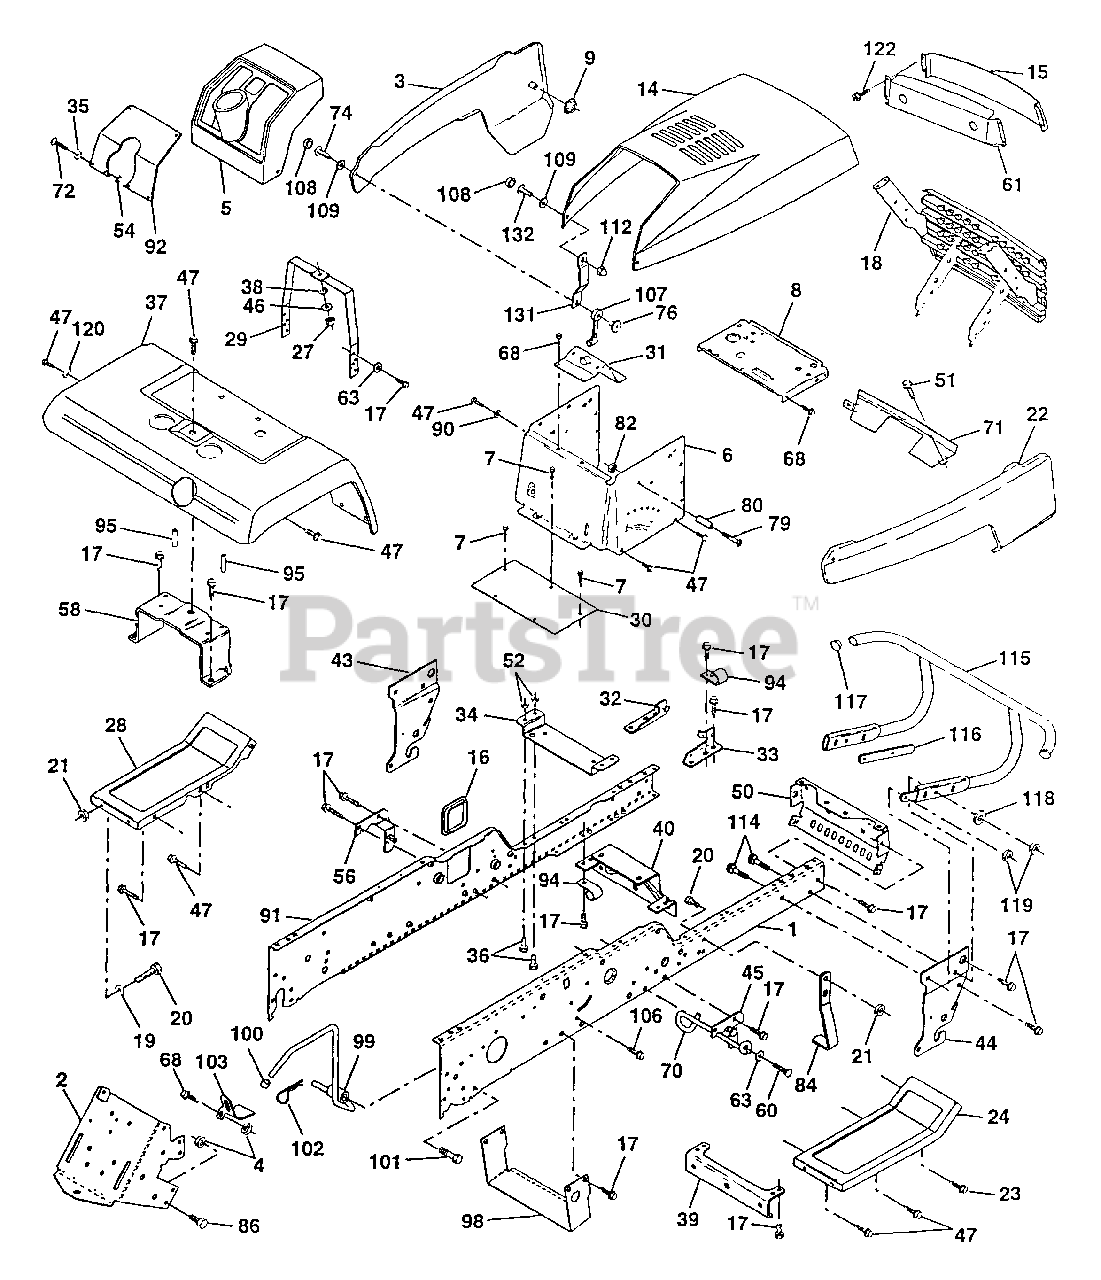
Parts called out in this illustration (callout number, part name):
1	Rail, Frame RH (AYP part number)
2	Drawbar, Gt (AYP part number)
3	Panel Asm., Side LH
4	Nut, Lock Hex 7/16 Unc
5	Dash, Plastic Black
6	Dash, 1PCS, Lower
7	Screw, Thd Cut 1/4-20 x 1/2
8	Support, Battery (AYP part number)
9	Nut, Pal
14	Hood Asm., Pnt
15	Lens, Headlight Bar
16	Cover, Access
17	Screw, Thdrol 3/8-16 x 3/4
18	Grille
19	Washer 13/32 x 13/16 x 12 Ga.
20	Bolt, Fin Hex 3/8-16 x 1
21	Nut, Crownlock 3/8-16
22	Panel Asm., Side RH (AYP part number)
23	Screw Thdrol 3/8-16 x 1
24	Footrest, RH (AYP part number)
27	Nut, Fin Hex 1/4-20
28	Footrest, LH
29	Bracket, Support Dash
30	Saddle
31	Bracket, Support Steering
32	Bracket Asm., Frame Pivot Lh
33	Bracket Asm., Frame Pivot Rh
34	Bracket, Engine Support Rear
35	Washer 11/32 x 11/16 x 16 Ga.
36	Bolt, Fin Hex 5/16-18 x 3/4
37	Fender, Pnt.
38	Washer, Lock 1/4
39	Bracket, Axle Front (AYP part number)
40	Bracket, Support Axle/Engine
43	Bracket, Spnsn Front Lh
44	Bracket, Spnsn Front Rh
45	Bracket Asm., Susp Chassis Rh
46	Washer 9/32 x 3/4 x 16 Ga.
47	Screw Thdrol 3/8-16 x 1/2
50	Bracket, Chassis Front
51	Screw Tap Tite 1/4-20 x 1/2
52	Nut, Crownlock 5/16-18
54	Nut 5/16-18
56	Bracket Asm., Susp Chassis Lh
58	Bracket Asm., Fender
60	Screw Thdrol 3/8-16 x 1-1/4
61	Beze. Asem. (AYP part number)
63	Washer 13/32 x 1 x 14 Ga. (AYP part number)
68	Screw, Thdrol 5/16-18 x 1/2
70	Guide, Belt Mid Span (AYP part number)
71	Strap, Grille
72	Screw, Mach Trhd 5/16-18 x 3/4
74	Screw, Machine #10-24
76	Nut, Weld #10-24
79	Screw, Machine #10-24 x 1/4
80	Spacer, Split
82	Nut #10-24
84	Stop, Over Center Mower
86	Bolt, Fin Hex 7/16-14 Unc x 1 (AYP part number)
90	Washer, Lock External Tooth 3/8
91	Rail, Frame Lh (AYP part number)
92	Plate, Silkscreen Dash (AYP part number)
94	Clip, Fuel Line
95	Push Nut, Nylon
98	Bracket Chassis Skid (AYP part number)
99	Rod Asm. Bypass
100	Cap Brake Parking Red
101	Screw Thdrol. 3/8-16 x 1-3/4
102	Retainer Spring 1"
103	Bracket Lock Bypass
106	Screw Thdrol Hex Head Zinc (AYP part number)
107	Latch, Chute Blk
108	Cap, Snap Black
109	Cap, Washer Snap Nat
112	Nut, Acorn, Hex #10-24
114	Bolt, Carriage 3/8-16 x 1-1/4
115	Bumper Asm.
116	Bracket Extension Bumper (AYP part number)
117	Plug, Plastic
118	Washer 13/32 x 13/16 x 16 Ga.
119	Nut, Crownlock 3/8-16 UNC
120	Washer 13/32 x 1 x 16 Ga.
122	Screw Spiderlock #8 x 7/8
131	Bracket Support Hood/Panel YP
132	Screw Truss Hd #10-24 x 3/8
